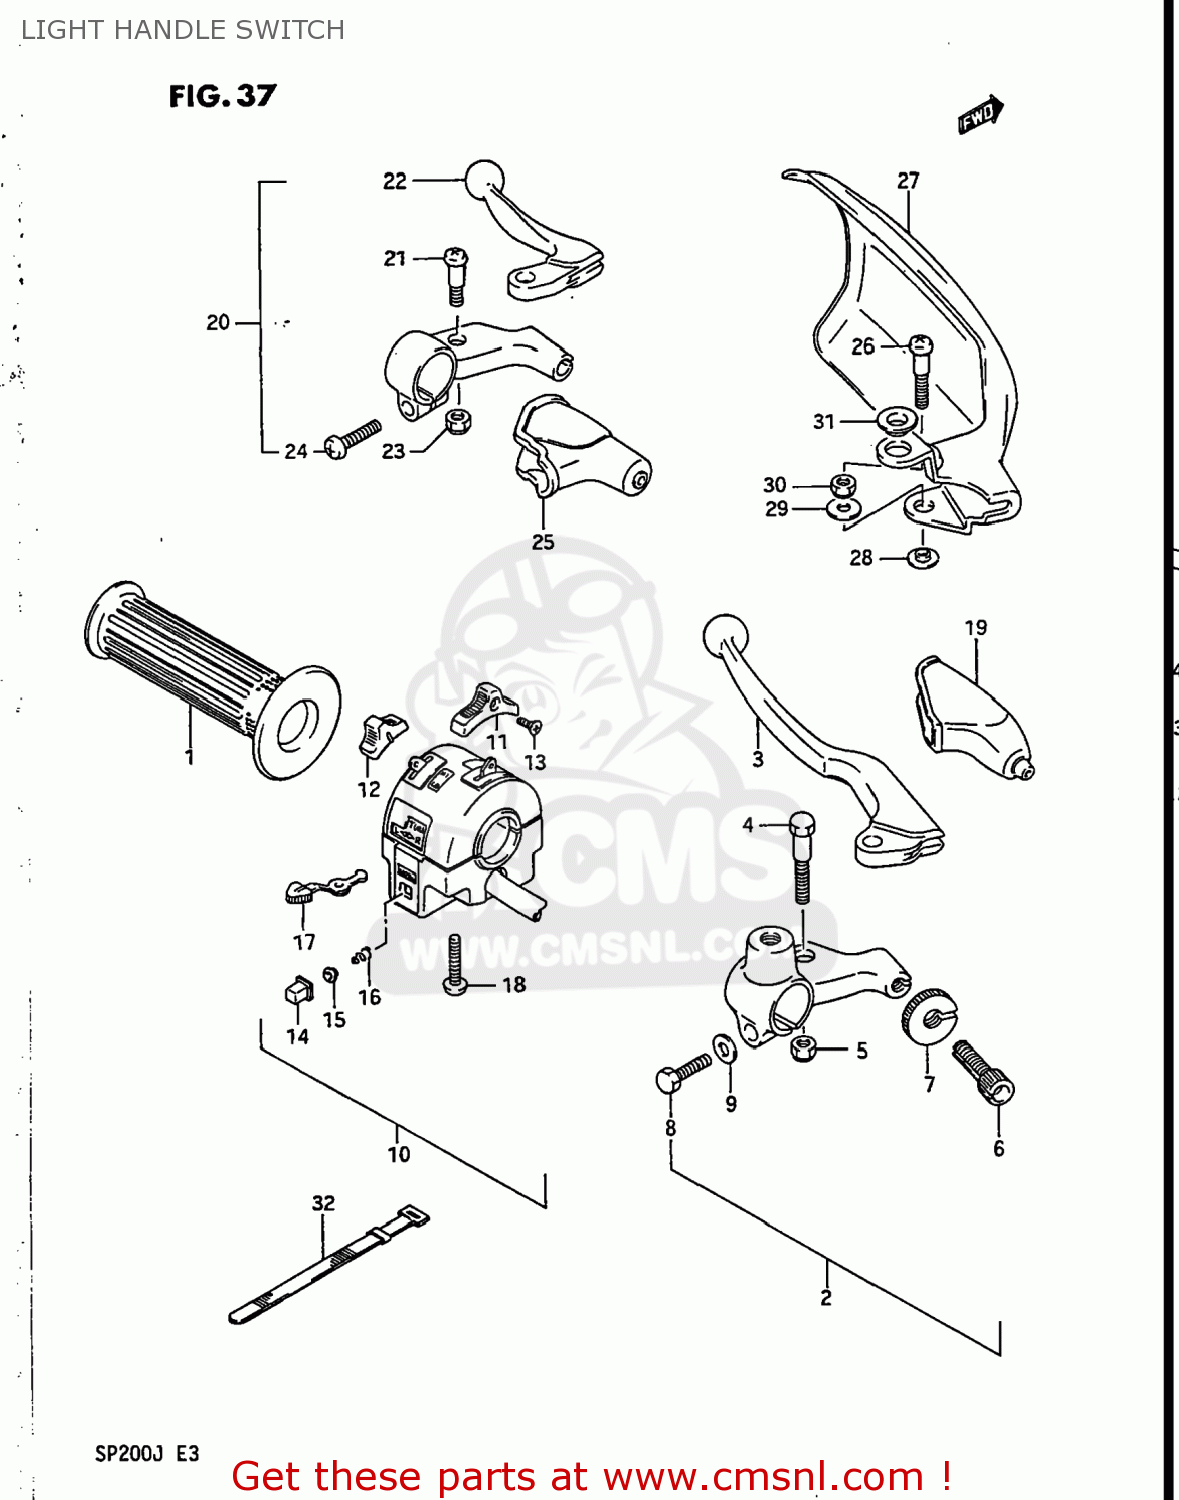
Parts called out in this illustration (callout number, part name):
1	GRIP,L
2	LEVER,CLUTCH
3	LEVER,CLUTCH
4	BOLT,LEVER PIVOT
5	NUT
6	ADJUSTER,CABLE
7	NUT,CABLE ADJUSTER LOCK
8	BOLT
9	WASHER
10	SWITCH ASSEMBLY,HANDLE,LEFT
11	KNOB,STOP
12	KNOB,DIMMER SWITCH
13	SCREW
14	BUTTON,HORN
15	CONTACT
16	SPRING
17	KNOB,TURNSIGNAL
18	SCREW
19	COVER,CLUTCH LEVER
20	LEVER ASSEMBLY,DECOMPRESSION
21	BOLT,LEVER
22	LEVER,DECOMP
23	NUT
24	SCREW
25	COVER,DECOMP LEVER DUST
26	BOLT,LEVER PIVOT
27	COVER,KNUCKLE,LEFT
28	WASHER
29	WASHER(6.5X16X1.2)
30	NUT 6MM
31	WASHER
32	CLAMP(L:120)
